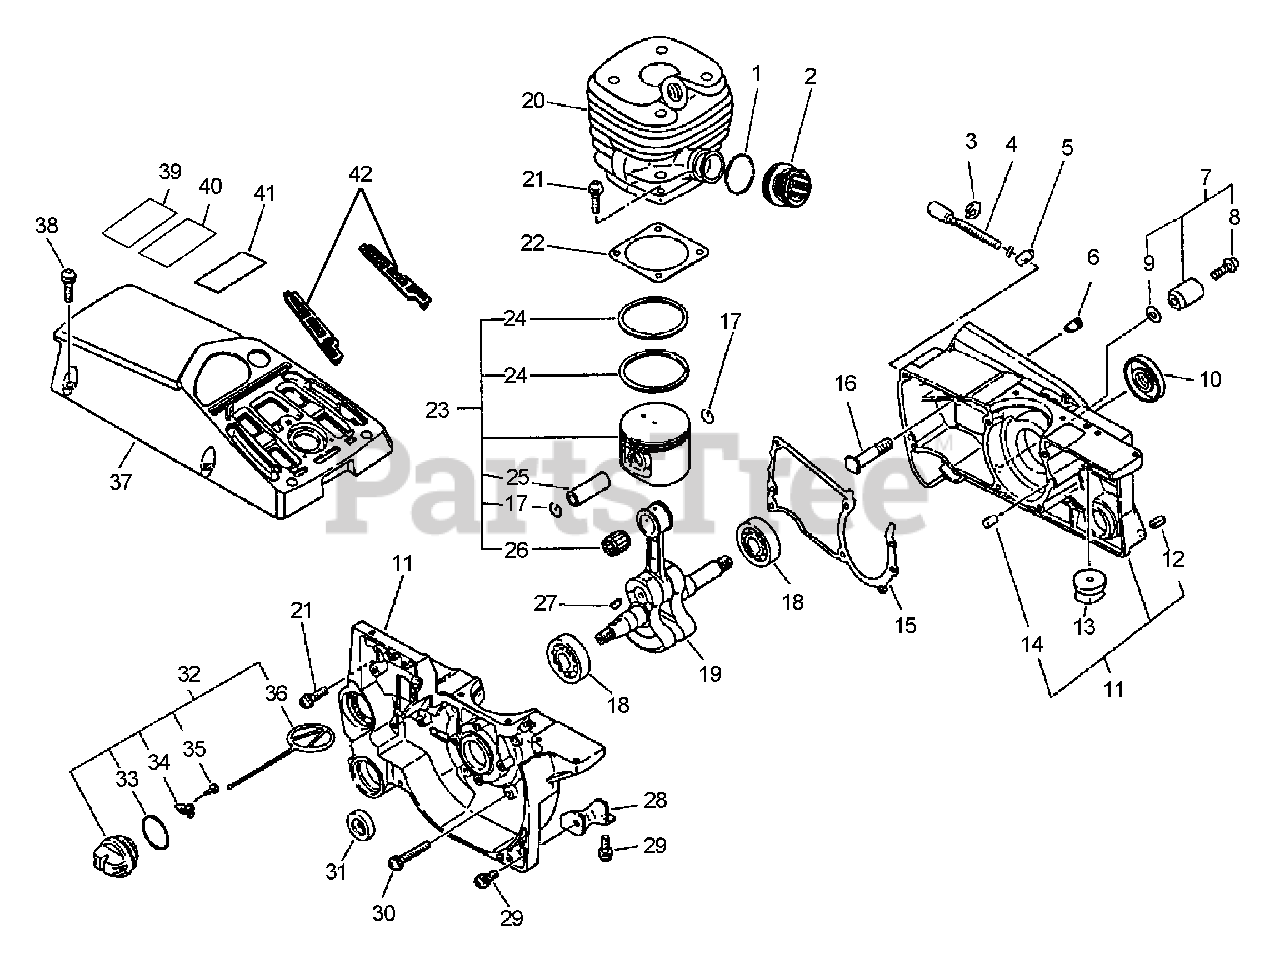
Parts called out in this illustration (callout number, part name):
2	ADAPTOR, INTAKE
4	SCREW, ADJUSTER
5	TENSIONER, CHAIN
6	VENT ASSY
7	CHAIN CATCHER KIT
8	SCREW 5×18
9	WASHER, FLAT 5.5×10×0.8
10	SEAL, OIL
11	CRANKCASE KIT
12	PIN, SPRING 5×10
14	PIN, LOCATING 5×10
15	GASKET, CRANKCASE
16	STUD, GUIDE BAR 8
17	RING, SNAP
18	BEARING, BALL 6202
19	CRANKSHAFT
20	CYLINDER KIT
21	BOLT 5×20
22	GASKET, CYLINDER
23	PISTON KIT
24	RING, PISTON
25	PIN, PISTON
26	BEARING, NEEDLE
27	KEY, WOODRUFF
29	BOLT 5×14
30	BOLT M5×35
31	SEAL, OIL
32	CAP ASSY, OIL
34	RETAINER, CONNECTOR
35	SCREW, TAPPING 3×8
36	CONNECTOR, CAP L= 60 MM
37	COVER, ENGINE
38	SCREW 5×20
39	LABEL, CAUTION
40	LABEL - KICK BACK
41	LABEL - KICK BACK
42	FILTER KIT
